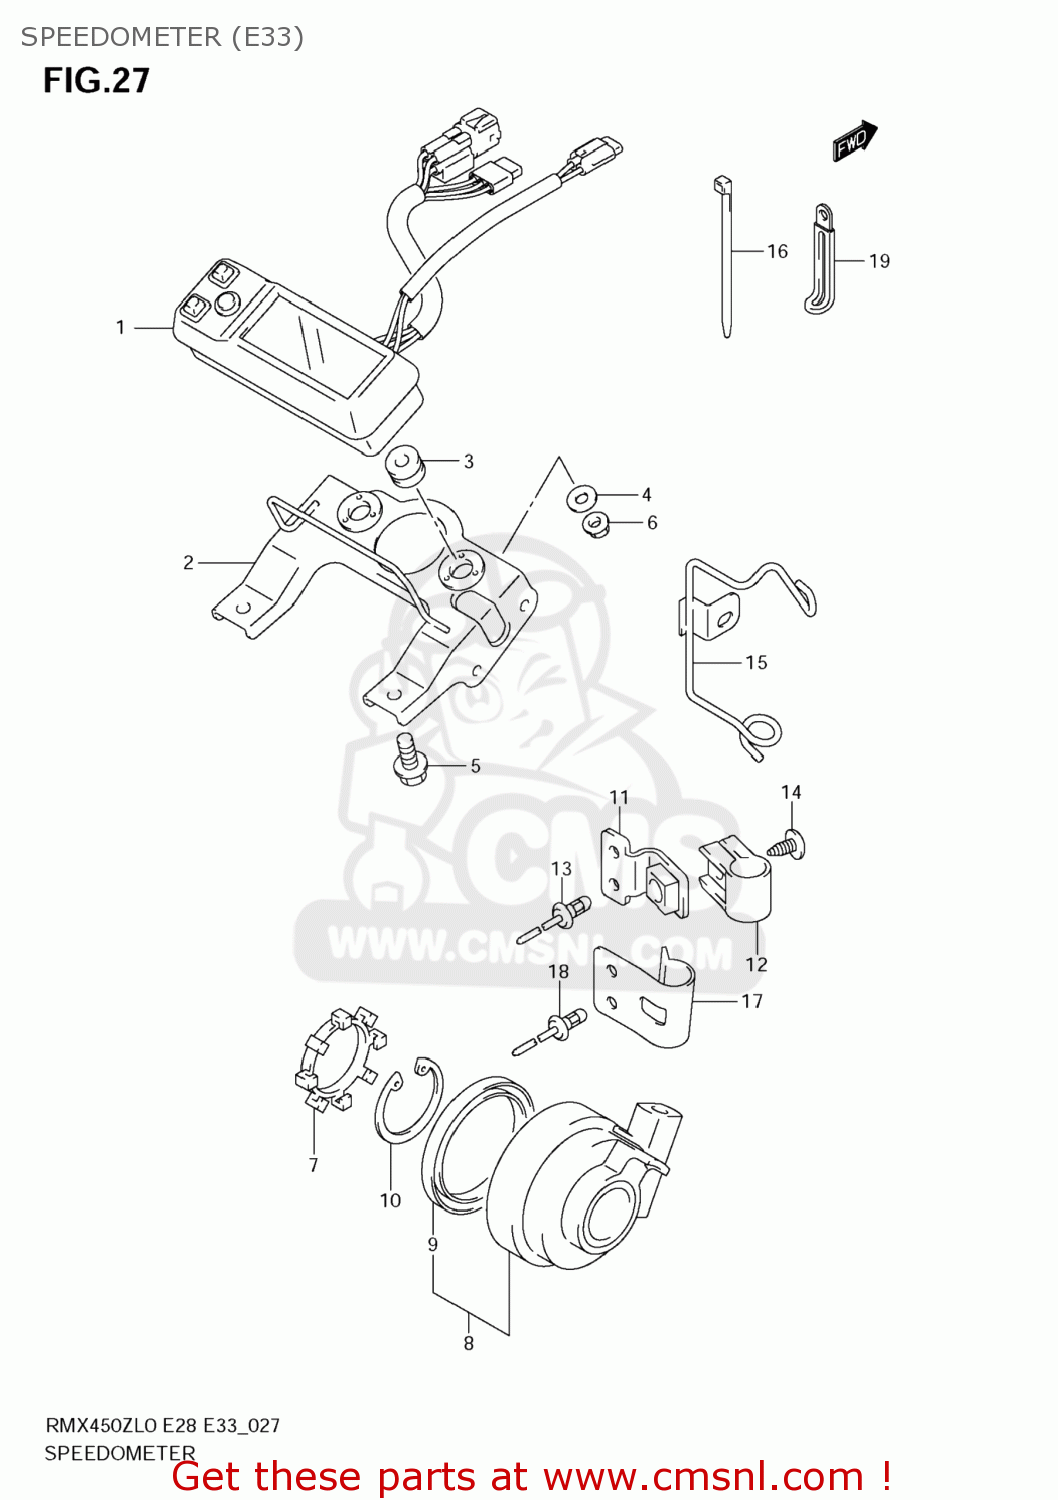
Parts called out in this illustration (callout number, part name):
1	SPEEDOMETER ASSY
2	BRACKET,SPEEDOMETER
3	CUSHION,SPEEDOMETER
4	WASHER(5.5X16X1.2)
5	BOLT
6	NUT
7	ROTOR,SPEED
8	SENSOR,SPEED
9	SEAL,OIL(48X62X7)
10	CIRCLIP
11	GUIDE,SENSOR NO.2
12	CLAMP,BRAKE HOSE
13	RIVET
14	SCREW
15	GUIDE,SENSOR NO.1
16	CLAMP(L:100)
17	GUIDE,SENSOR NO.3
18	RIVET
19	CLAMP(L:45)
